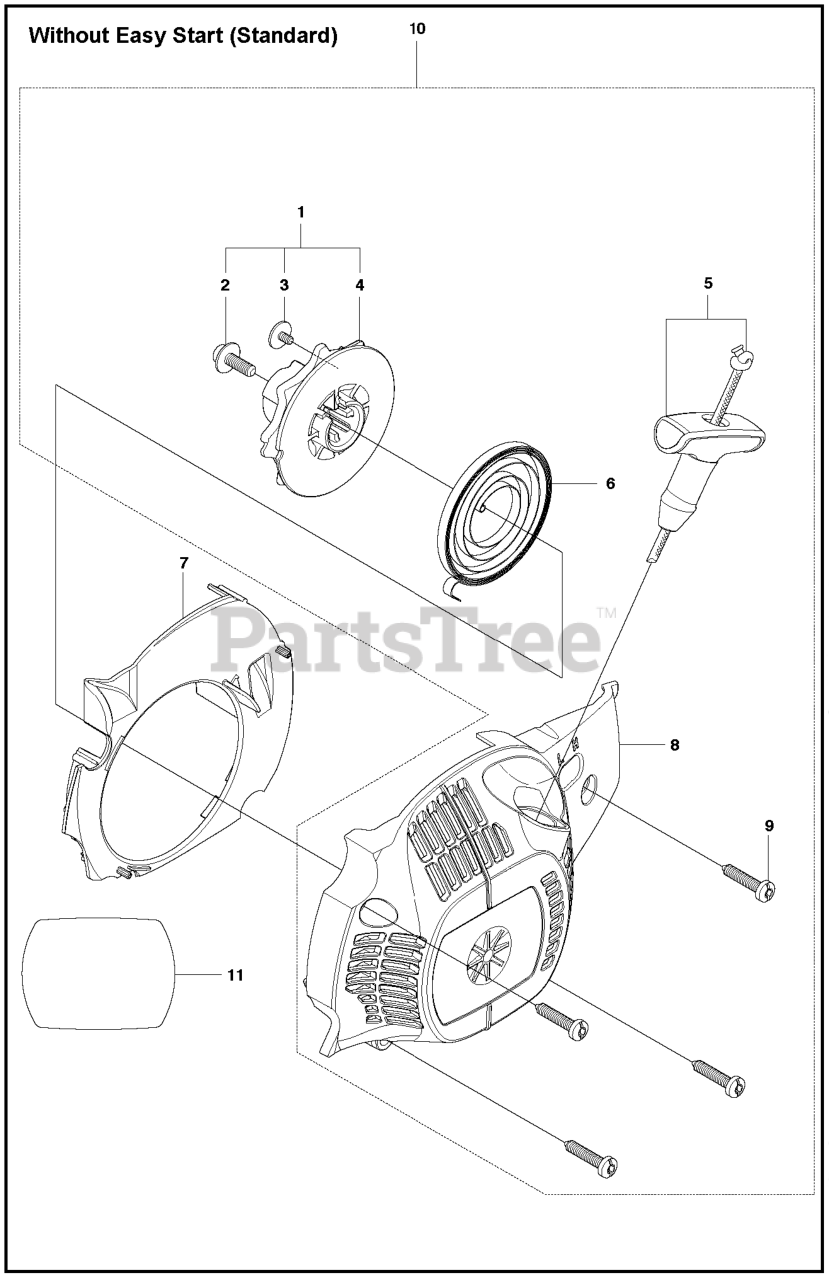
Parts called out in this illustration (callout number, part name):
1	KIT, STD STARTER
2	SCREW
3	SCREW
4	STARTER PULLEY
5	STARTER ROPE W/HANDLE
6	SPRING STARTER
7	BAFFLE
8	FAN HOUSING
9	SCREW M5.38-14X22.225MM
10	STARTER KIT COMPLETE 235/240
11	Decals
